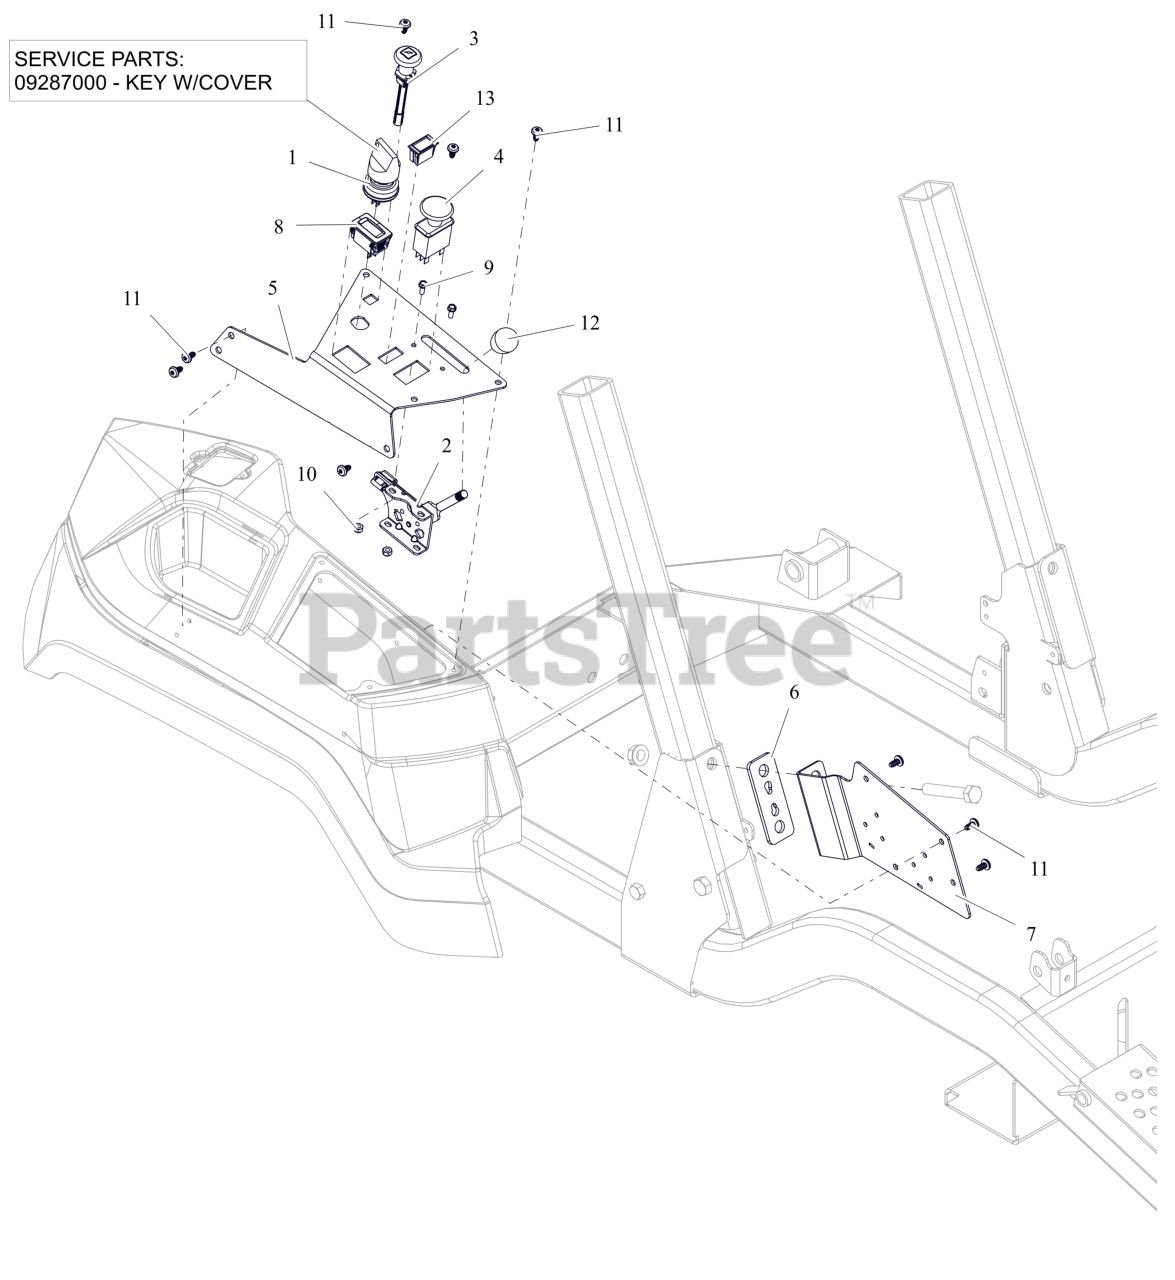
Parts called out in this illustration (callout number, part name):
1	SWITCH, IGNITION
2	CABLE, PRO THROTTLE CONTROL
3	CABLE - CHOKE, SNAP-IN
4	SWITCH, CLUTCH
5	PLATE, APEX CONTROL PANEL
6	PLATE, CONTROL PANEL SPACER
7	BRKT, FENDER/RELAY MOUNTING
8	HOUR METER
9	BLT, HWH #10-24X.50 ZCC
10	NUT-LK-NYL #10-24 G2 ZCC
11	SCR-PAN .25-15X.50 6L H/LZB500
12	KNOB-CONTROL-BLACK .38-16X.50
13	SWITCH,BLANK
